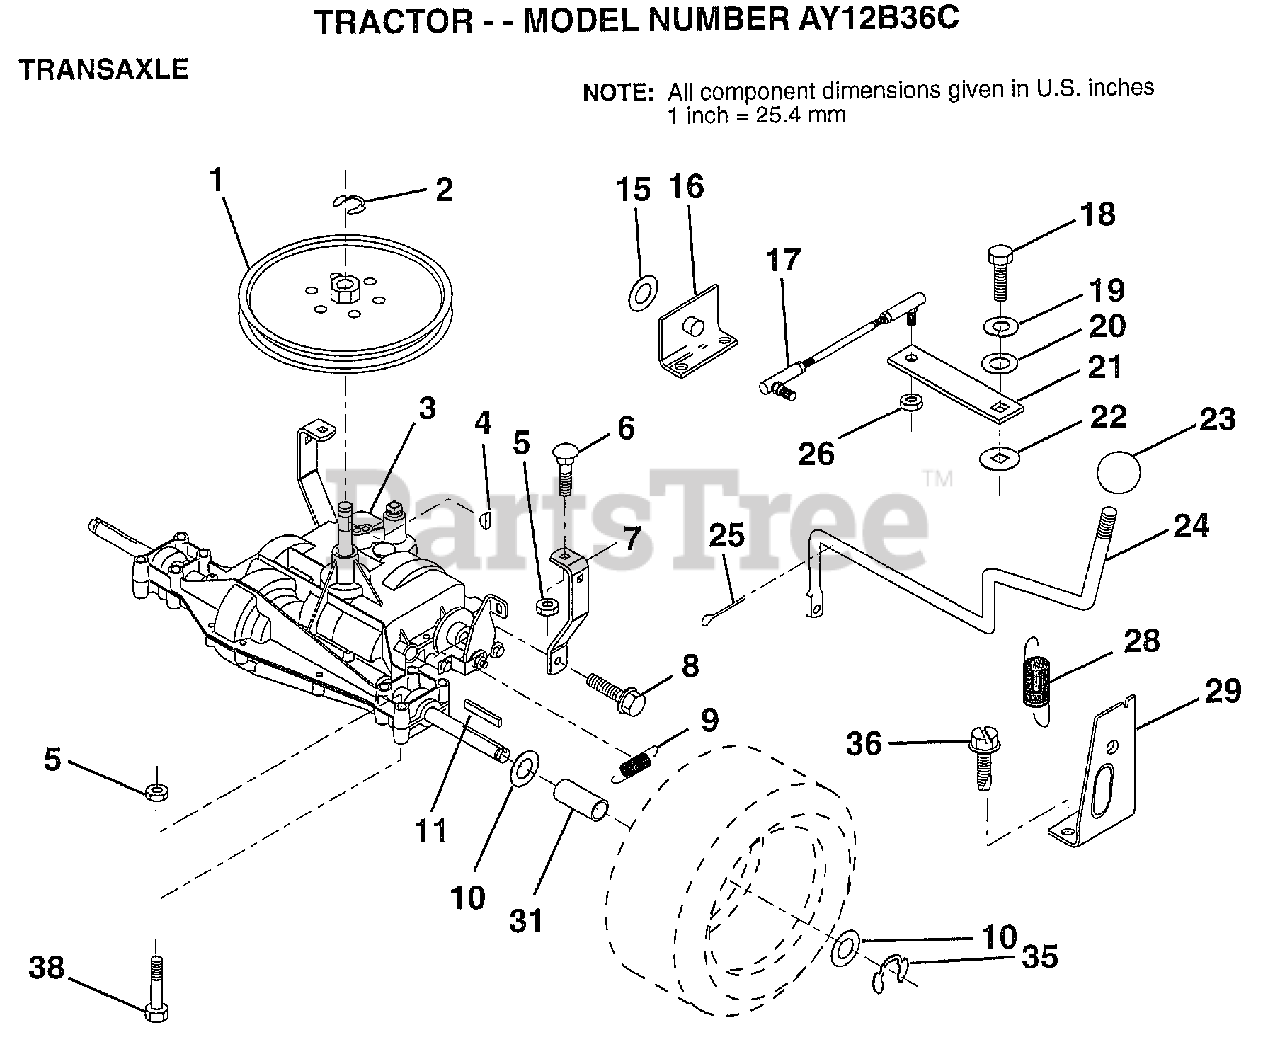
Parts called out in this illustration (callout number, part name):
1	PULLEY
6	BOLT
7	"STRAP,TORQUE"
8	SCREW
9	SPRING.BRAKE.RETU
10	WASHER
11	SQUARE KEY
16	"SUPT,HDLE SHT LH"
17	LINK SHIFT
18	BOLT.1/4-28.W/PAT
19	LOCKWASHER
20	WASHER LT
22	WASH-SHFT PLT LT
23	KNOB T (1/2-HOLE)
24	"ROD,SHIFT"
25	PIN COTTER 1/8
26	NUT.LOCK.5/16-24
28	"SPRING,EXT"
29	"SUPT,HDLE RH"
31	SPACER AXLE
35	E-RING LT
36	SCREW
38	BOLT.HEX.FLGHD
